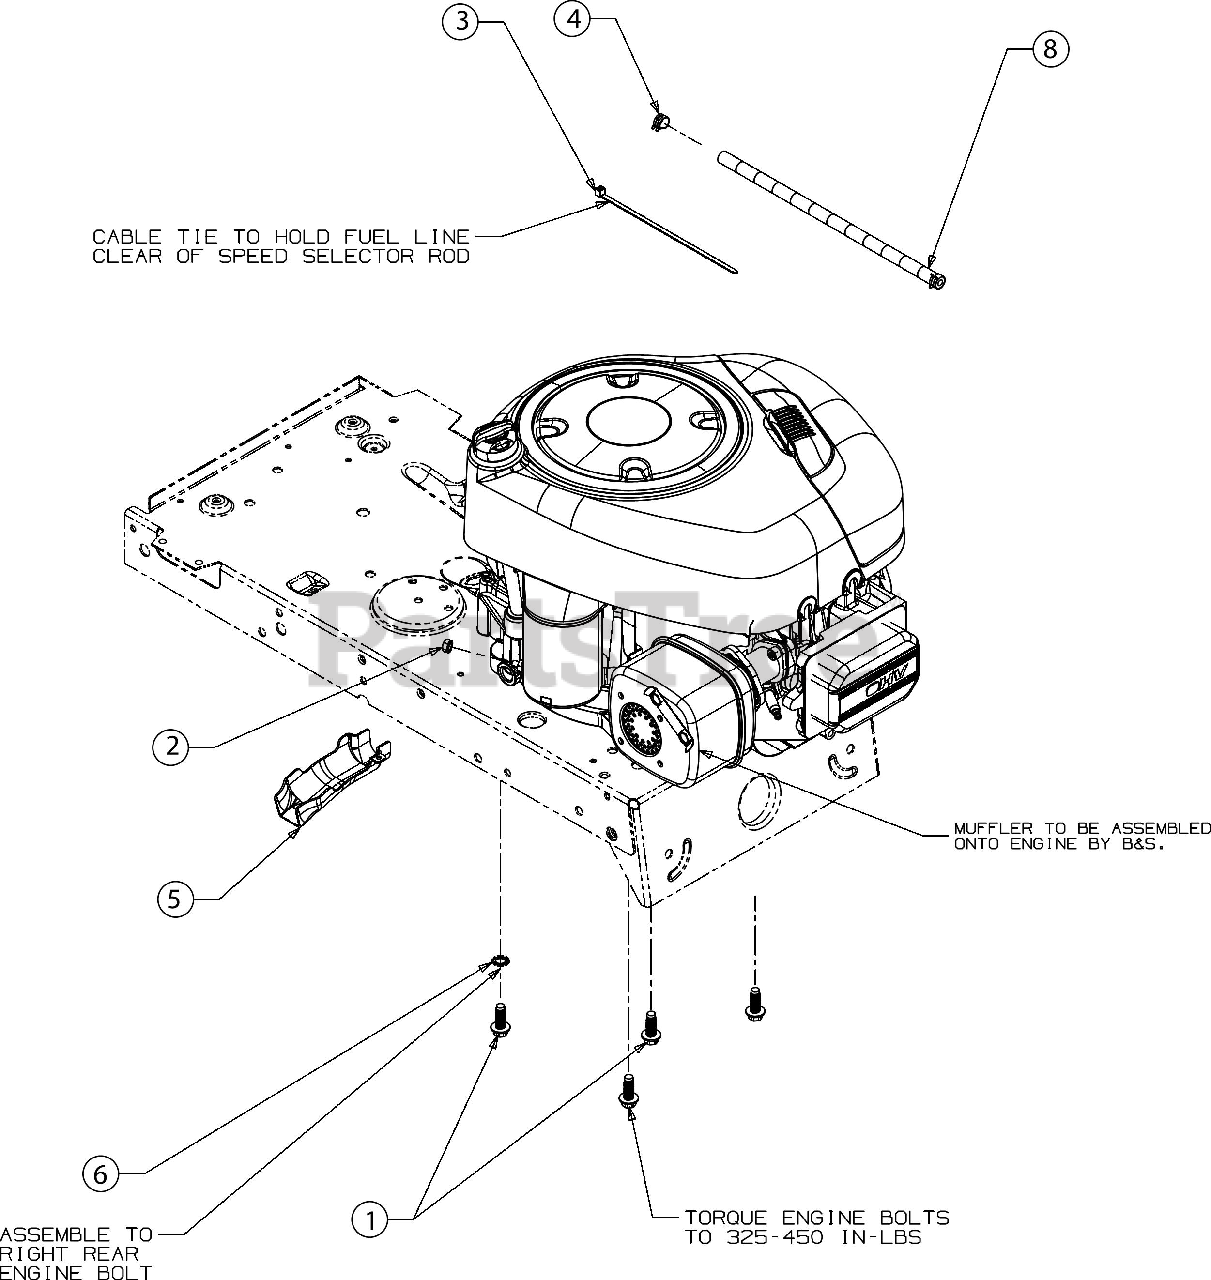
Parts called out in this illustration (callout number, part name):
1	SCREW 3/8-16 X 1
2	SEMS NUT 1/4-20
3	CABLE TIE 7"
4	HOSE CLAMP 1/20
5	OIL DRAIN SLEEVE
6	LOCK WASHER 3/8
8	FUEL HOSE LOW PERMEATION
